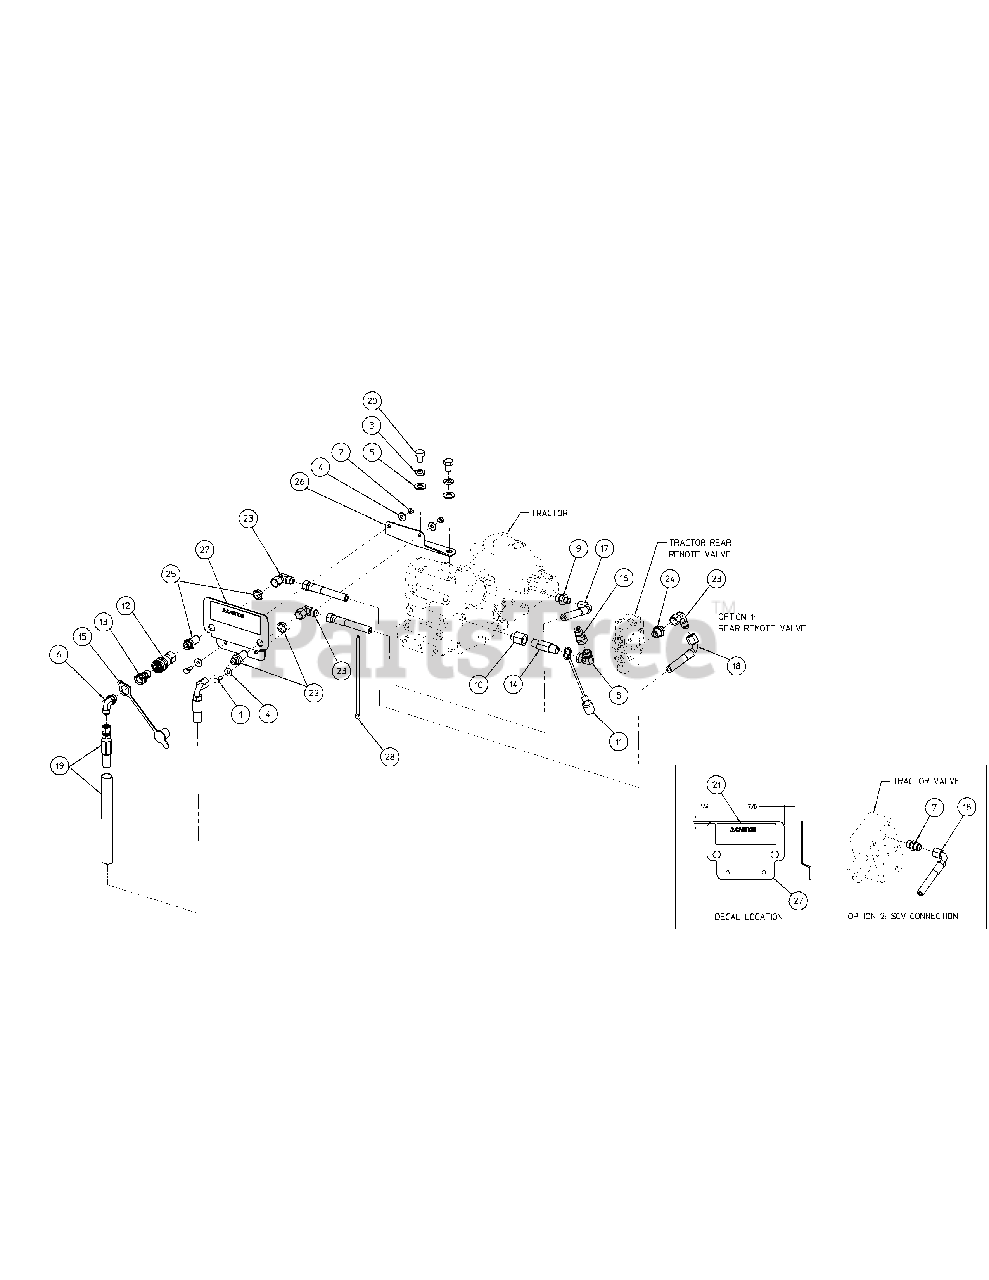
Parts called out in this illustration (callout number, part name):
1	BOLT HEX, 5/16-24 X .75 GR 5 SAE
2	NUT LOCK, 5/16-24
3	LOCK WASHER, 9/16
4	FLAT WASHER, 5/16
5	FLAT WASHER HARDENED, 9/16 SAE
6	ADAPTER FLARE, ELBOW 90
7	ADAPTER STRAIGHT, 37 DEG FLARE
8	ADAPTER UNION, ELBOW 90
9	ADAPTER 37 FLARE (STR MALE)
10	ADAPTER PIPE
12	COUPLER BODY
13	COUPLER NOSE
14	HYD NIPPLE
16	COUPLER NOSE
17	HOSE HYD 3/8 X 30"
18	HOSE HYD 3/8 X 48"
19	HOSE HYD WITH SLEEVE 1/2 X 23"
20	BOLT M14-2.00 X 20 GR 10.9
21	DECAL CAUTION
22	BULKHEAD UNION
23	ADAPTER UNION, ELBOW 90
24	ADAPTER FLARE
25	ADAPTER UNION
26	PLATE, BRACKET MOUNT
27	PLATE, CONNECTOR MOUNT
28	PLASTIC TIE
